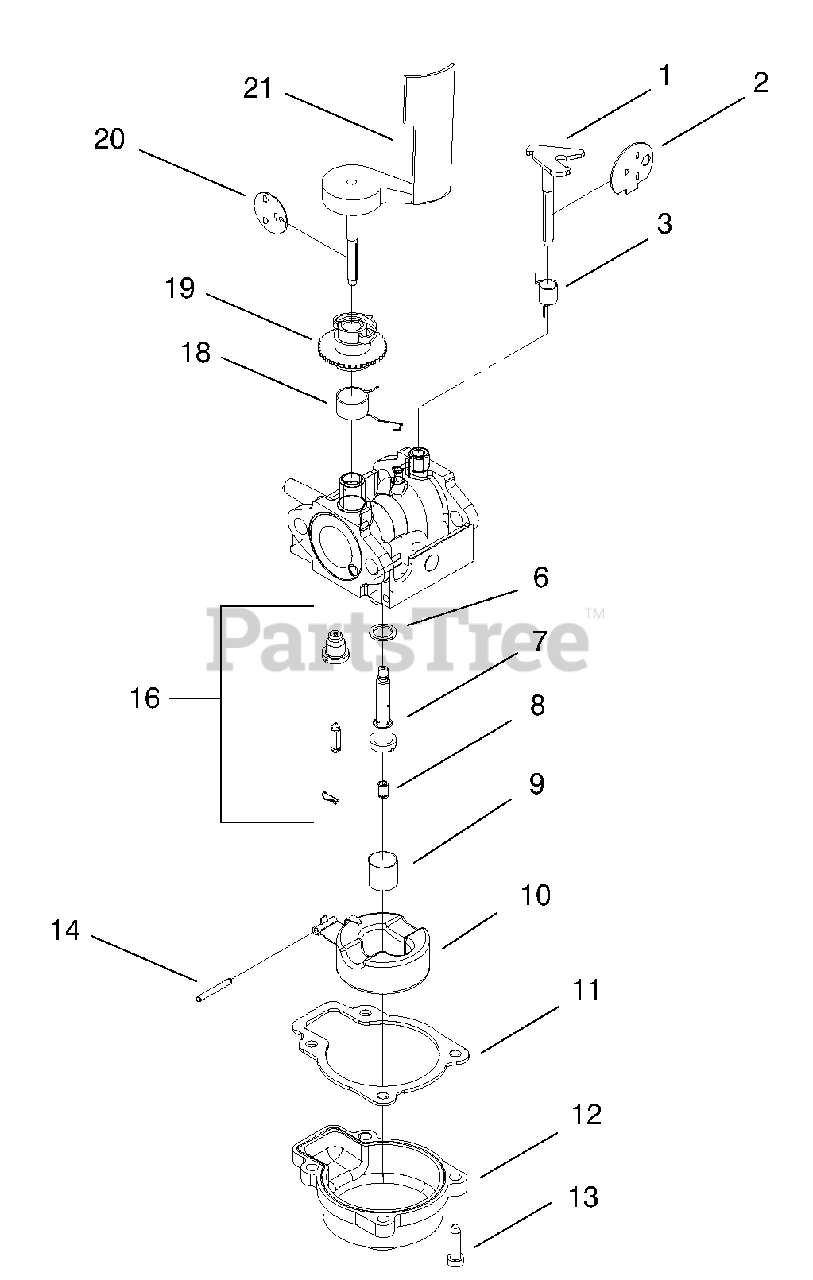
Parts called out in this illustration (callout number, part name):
1	Shaft-Choke
2	Disc-Choke
3	Spring-Choke
8	Jet-Main
9	Filter-Fuel
10	Float & Arm ASM
12	Chamber-Float
13	Screw-HH
14	Pin-Straight
16	Val/Seat-Float
18	Spring-Throttle
19	Collar-Adjust, Airvane
20	Disc-Throttle
21	Air Vane & Shaft
